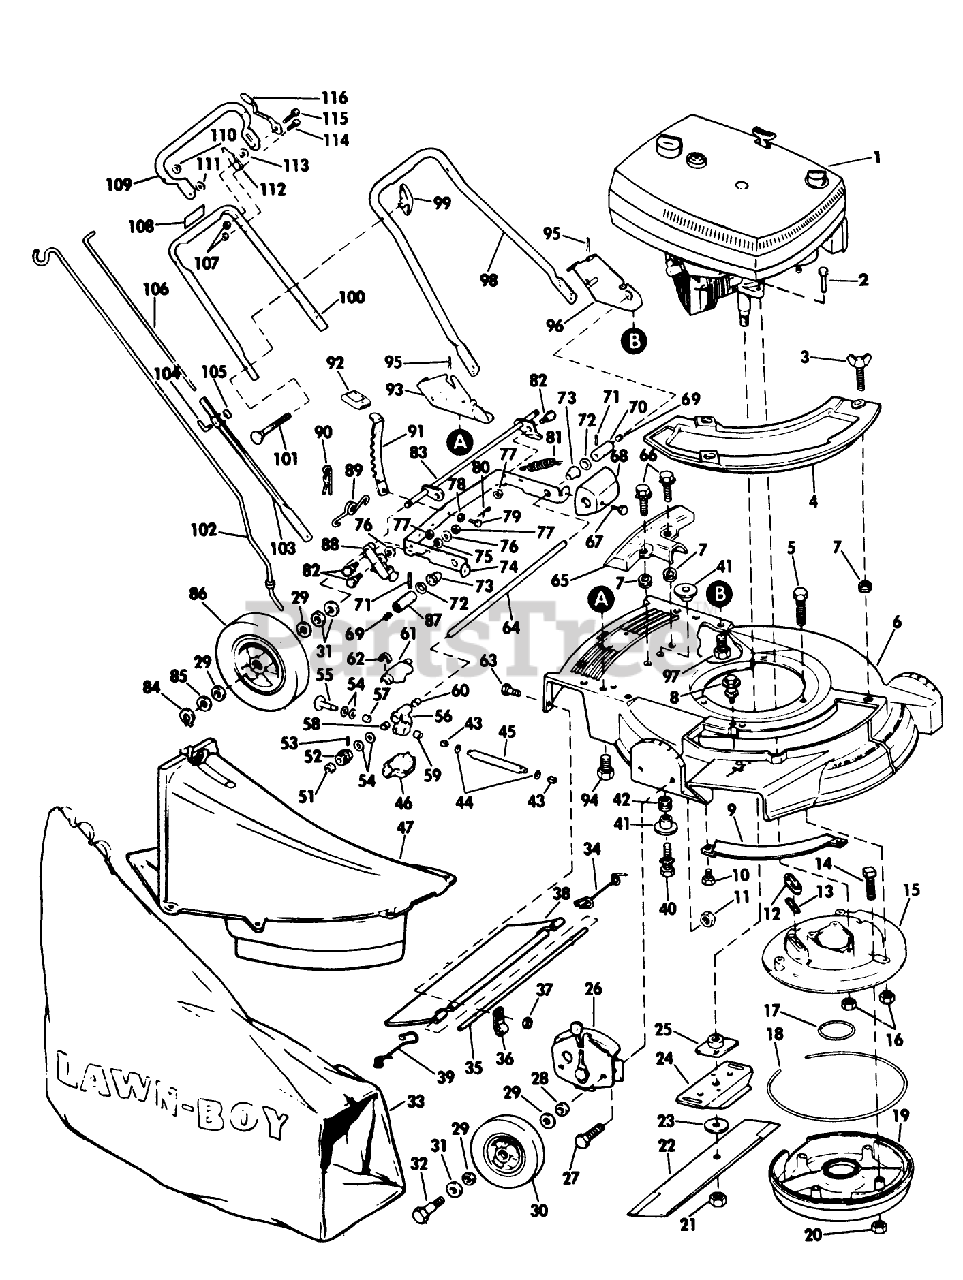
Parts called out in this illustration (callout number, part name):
1	Note #2 at bottom of this page.
2	BOLT F
3	WING SCREW LAWRE
5	SCREW V
9	BAR-TOE
11	NUT-LOCK F
12	SLEEVE
13	GASKET S
14	SCREW
16	NUT-LOCK F
18	Gasket Muffler (outside)
20	LOCKNUT E
21	NUT-BLADE
23	WASHER
25	PLATE AND COLLAR ASM
28	WASHER WROUGHT
29	WASHER
30	WHEEL & TIRE KIT
31	SPACER
32	BOLT WHEEL
33	ORD LB 89802 WHOLE GOODS
34	SPRIG T/SHLD ASOC
35	ROD 21" ADVANCE
36	CLAMP ROD KMC
37	LOCKNUT E
39	SPRING;TRAILING SHIELD RH
41	SPACER ECK PRES
42	GROMMET
43	BUSHING
44	O Ring
51	WASHER
53	ROLL PIN
54	THRUST WASHER
57	NEEDLE BEARING
61	GEAR COVER UPPER
64	DRIVE SHFT TAG AY
65	COVER
66	SCREW SEMS TRM HEX HD
68	GUARD
69	GREASE PLUG
71	PIN
76	WASHER S
77	STOP NUT
78	WASHER SPRING LAR
79	PIN
81	SPRING
82	BOLT RB&W
84	RET RING
85	SPACER
89	SPRING N.A.S
91	LEVER
92	KNOB
94	SCREW
95	HAIR PIN
97	SCREW
99	NUT-WING
100	HANDLE
102	ROD GRASSBAG
106	ROD CONTROL
107	LOCKNUT E
111	WASHER M
115	BOLT RB&W
116	KNOB & SPRING
